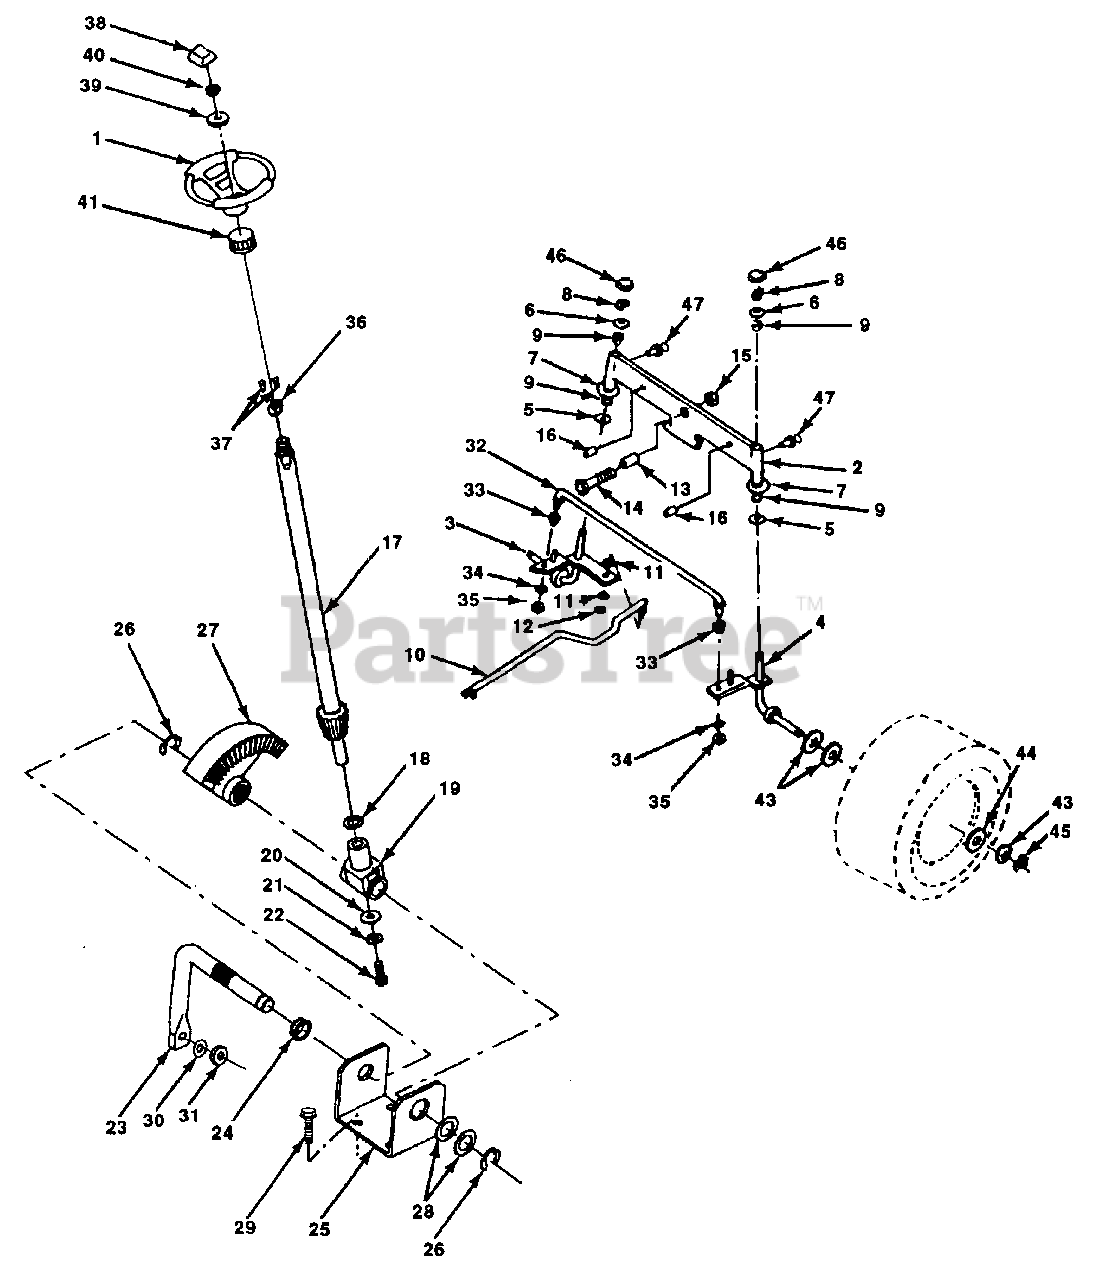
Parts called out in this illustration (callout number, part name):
1	Steering Wheel (AYP part number)
2	Axle Assembly, Front (AYP part number)
3	Spindle Assembly, L.H.
4	Spindle, Assembly, R.H.
5	Bearing, Thrust (AYP part number)
6	Washer 25/32 x 1-5/8 x 16 Gauge (AYP part number)
7	Washer 27/32 x 1-1/4 x 16 Gauge (AYP part number)
8	Ring, Klip (AYP part number)
9	Bearing (AYP part number)
10	Link, Drag (AYP part number)
11	Washer, Lock 3/8 (AYP part number)
12	Nut, Hex 3/8-24 (AYP part number)
13	Spacer, Bearing (AYP part number)
14	Bolt, Hex 5/8 - 11 unc x 3-1/2 (AYP part number)
15	Locknut, Flange 5/8-16 (AYP part number)
16	Pin, Axle 5/8 - 1.55/1.54 (AYP part number)
17	Shaft Assembly, Steering (AYP part number)
18	Washer (AYP part number)
19	Support, Shaft (AYP part number)
20	Washer, Shim 1/4 x 5/8 x .062 (AYP part number)
21	Washer, Lock 1/4 (AYP part number)
22	Screw, Socket, Hex 1/4-20 x 5/8 (AYP part number)
23	Shaft, Pitman (AYP part number)
24	Nyliner, Snap In (AYP part number)
25	Bracket, Steering (AYP part number)
26	Ring, Klip (AYP part number)
27	Gear, Sector (AYP part number)
28	Bearing, Thrust (AYP part number)
29	Screw, Hex Washer Head, Thread Forming 3/8- 16 x 3/4 Type TT (AYP part number)
30	Washer, Lock Hvy Hlcl Spr 3/8 (AYP part number)
31	Nut, Fin Hex 3/8 - 24 UNF (AYP part number)
32	Rod, Tie (AYP part number)
33	Washer 11/32 x 3/4 x 16 Gauge (AYP part number)
34	Washer, Lock 5/16 (AYP part number)
35	Nut, Hex 5/16-24 (AYP part number)
36	Bushing Strg Blk (AYP part number)
37	Screw, Slftp #10 - 16 x 1/2 (AYP part number)
38	Insert, Steering Wheel (AYP part number)
39	Washer 17/32 x 2-1/4 x .160 (AYP part number)
40	Nut, Hex, Toplock Jam 1/2-20 (AYP part number)
41	Adapter, Steering Wheel (AYP part number)
43	Washer 25/32 x 1-1/4 x 16 Gauge (AYP part number)
44	Washer 25/32 x 1-5/8 x 16 Ga. (AYP part number)
45	Ring, Klip (AYP part number)
46	Cap, Spindle (AYP part number)
47	Fitting Grease (AYP part number)
